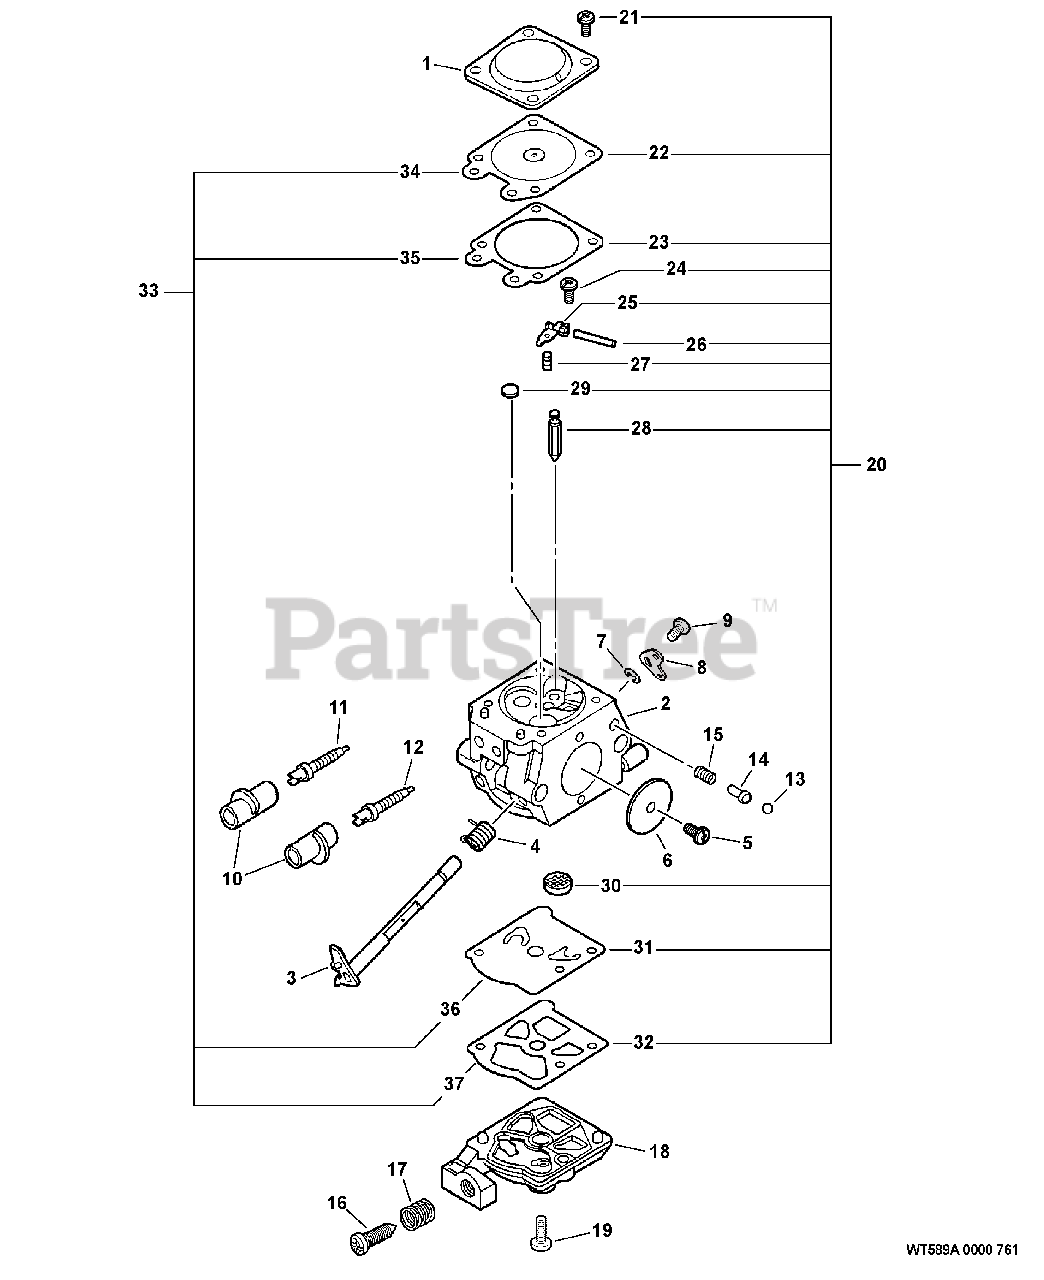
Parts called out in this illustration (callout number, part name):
1	COVER, METERING DIAPHRAGM
2	BODY, CARBURETOR
3	SHAFT, THROTTLE
4	SPRING, THROTTLE
6	VALVE, THROTTLE
8	LEVER, THROTTLE
10	CAP, LIMITER
11	NEEDLE, HIGH SPEED
12	NEEDLE, MIXTURE
14	PISTON ASSY
15	SPRING, START VALVE
16	SCREW, IDLE ADJUST
17	SPRING, IDLE ADJUST
18	COVER, FUEL PUMP
20	REPAIR KIT, CARBURETOR
22	DIAPHRAGM, METERING
23	GASKET, DIAPHRAGM
24	SCREW, METERING LEVER PIN
25	LEVER, METERING
26	PIN, METERING LEVER
27	SPRING, METERING LEVER
28	VALVE, INLET NEEDLE
29	PLUG, WELCH
30	STRAINER
31	DIAPHRAGM, PUMP
32	GASKET, PUMP
33	GASKET / DIAPHRAGM KIT
34	DIAPHRAGM, METERING
35	GASKET, DIAPHRAGM
36	DIAPHRAGM, PUMP
37	GASKET, PUMP
